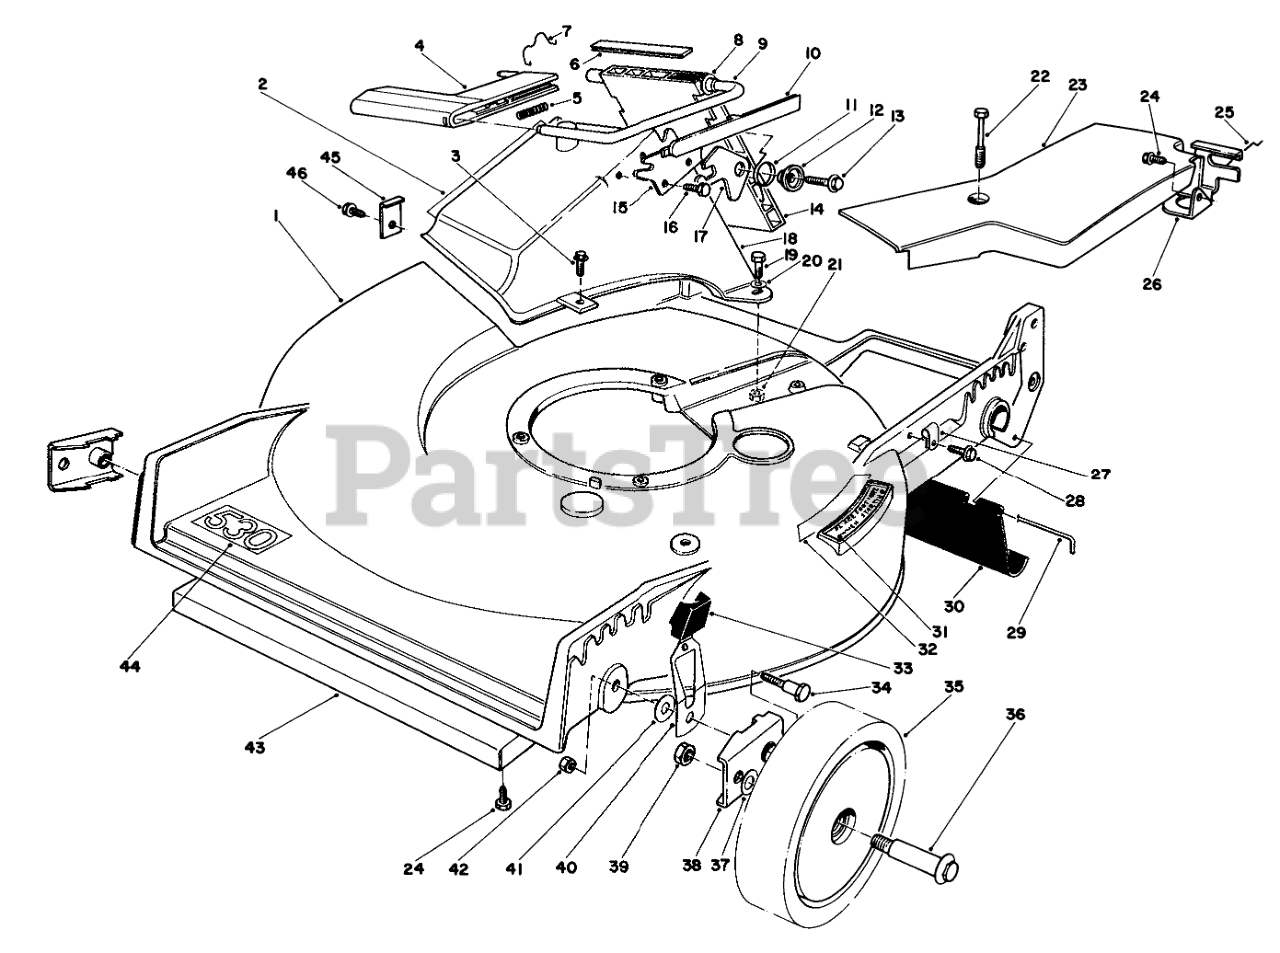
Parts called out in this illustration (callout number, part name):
1	21 SP RB HSG/DECAL
2	ATTENTION DECAL
3	Screw
4	Handle-Door
5	Spring
6	Cover-Door
7	DOOR RET SPRING
8	BUSHING-NYLON
9	DOOR ROD +
10	DOOR HANDLE COVER
11	Spring-Torsion
12	DOOR SPACER
13	SCREW-HWH
14	Door Discharge
15	DOOR LATCH PLATE
16	SCREW-PLASTITE
17	Latch-Door
18	Tunnel Discharge
19	SCREW-HH
20	WASHER-FLAT
21	NUT-LOCK, NI
22	SCREW-HHFTF
23	Cover-Belt
24	SCREW-HWHTF
25	RETAINER-CABLE
26	Bracket-Traction Adj.
27	CLAMP-CABLE
28	SCREW
29	ROD-SHIELD
30	SHIELD-TRAILING
31	STEP PAD DECAL
32	Decal-Place Foot Here
33	KNOB-ARM
34	PIVOT SCREW
35	Wheel & Tire Assembly
36	BOLT-WHEEL
37	WASHER
38	HP PIVOT ARM ASM
39	Nut
40	Spring Arm
41	Washer
42	NUT-LOCK, NI
43	Shield-front
44	Decal-530
45	TUNNEL CLIP
46	SCREW
